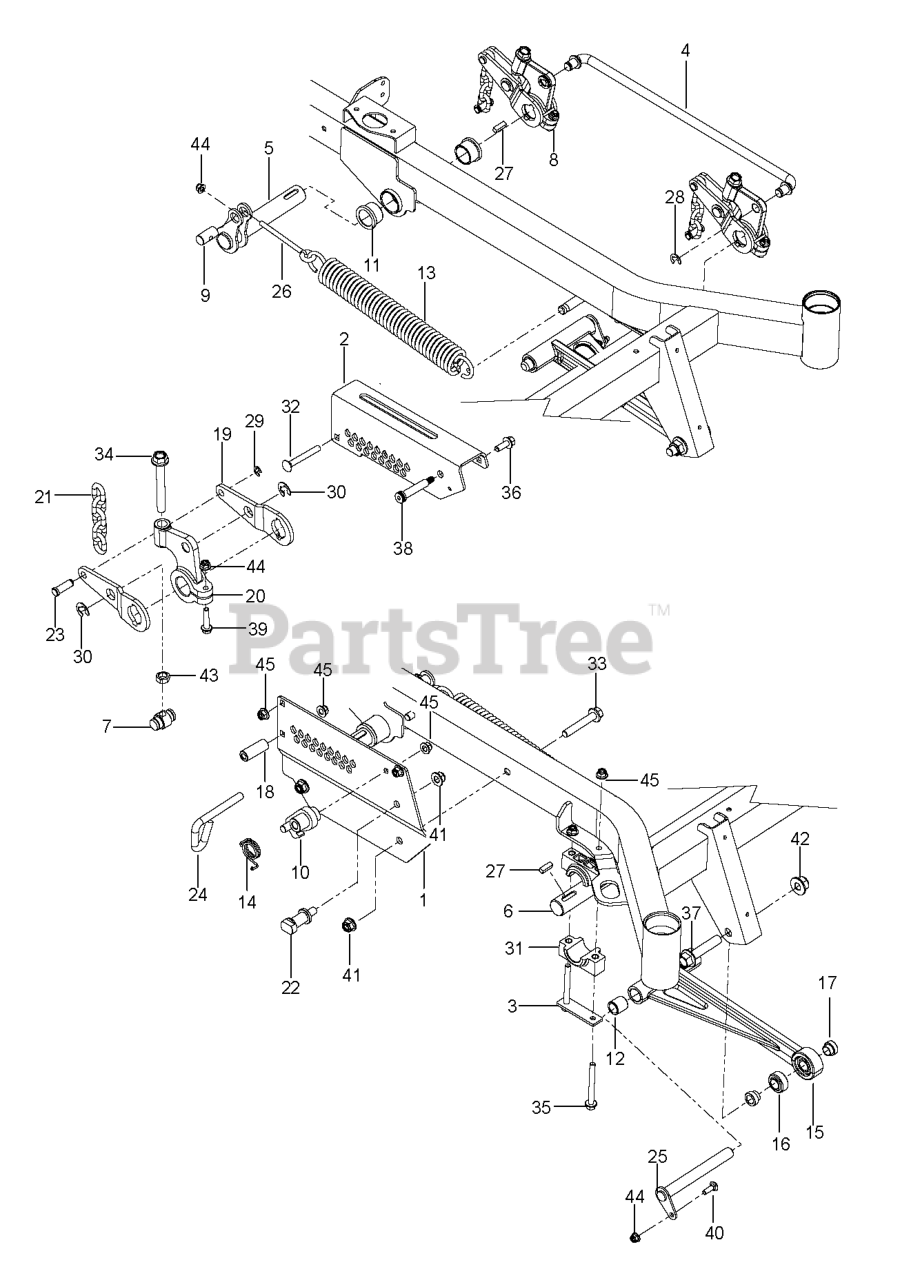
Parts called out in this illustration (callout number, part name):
1	PLATE INNER HEIGHT SNAPPER RED
2	PLATE OUTER HEIGHT SNAPPER RED
3	PLATE, PILLOW BLACK
4	ROD, LIFT
5	SHAFT, RR LIFT
6	SHAFT, LIFT, FT
7	SHAFT, LIFT TRUNION WSL
8	ASSEMBLY, DECK LIFT CRANK
9	PIVOT, SPRING
10	LATCH, TRANSPORT WLDMT
11	BUSHING, FLANGE 1.25 X 1.0
12	BUSHING, SLEEVE 3/4 X 1.0
13	SPRING, EXTENSION
14	SPRING, TORSION
15	ASSEMBLY, STRUT
16	BALL JOINT, 3/4" SWIVEL
17	SPACER, STRUT
18	SPACER, HEIGHT PLATE
20	ARM, CAST LIFT
21	LIFT CHAIN
22	GUIDE, HEIGHT BAR
23	PIN, 7/16 CLEVIS
24	PIN, HEIGHT
25	PIN, STRUT
26	EYE BOLT 4.5`
27	KEY, 5/16 SQ X 1.0
28	E-RING 5/8
29	RING, E, 7/16
30	E RING 3/4
31	BLOCK, PILLOW
32	3/8-16 X 3` CARR BOLT
33	HFFS 1/2-13 X 3 GD 5 ZD
34	HHFS 1/2-13 X 4 GR 5
35	HHFS 3/8-16 X 3.5 GD 5 ZD
36	HHFS 3/8-16 X 1 GRD 5 ZD
37	HHFS 5/8-11 X 3.0 GD 8 ZD
38	BOLT, SHOULDER, 1/2 X 2.25
39	HHFS 5/16-18 X 1.5 GD 5
40	BOLT CRT
41	NUT, 1/2-13 HEX FLG NYLOC ZD
42	NUT 5/8-11 FLG NYLOC ZD
43	NUT 1/2 HEX JAM
44	5/16-18 NYLOC FLANGE NUT
45	NUT 3/8-16 HEX FLG NYLOC ZD
